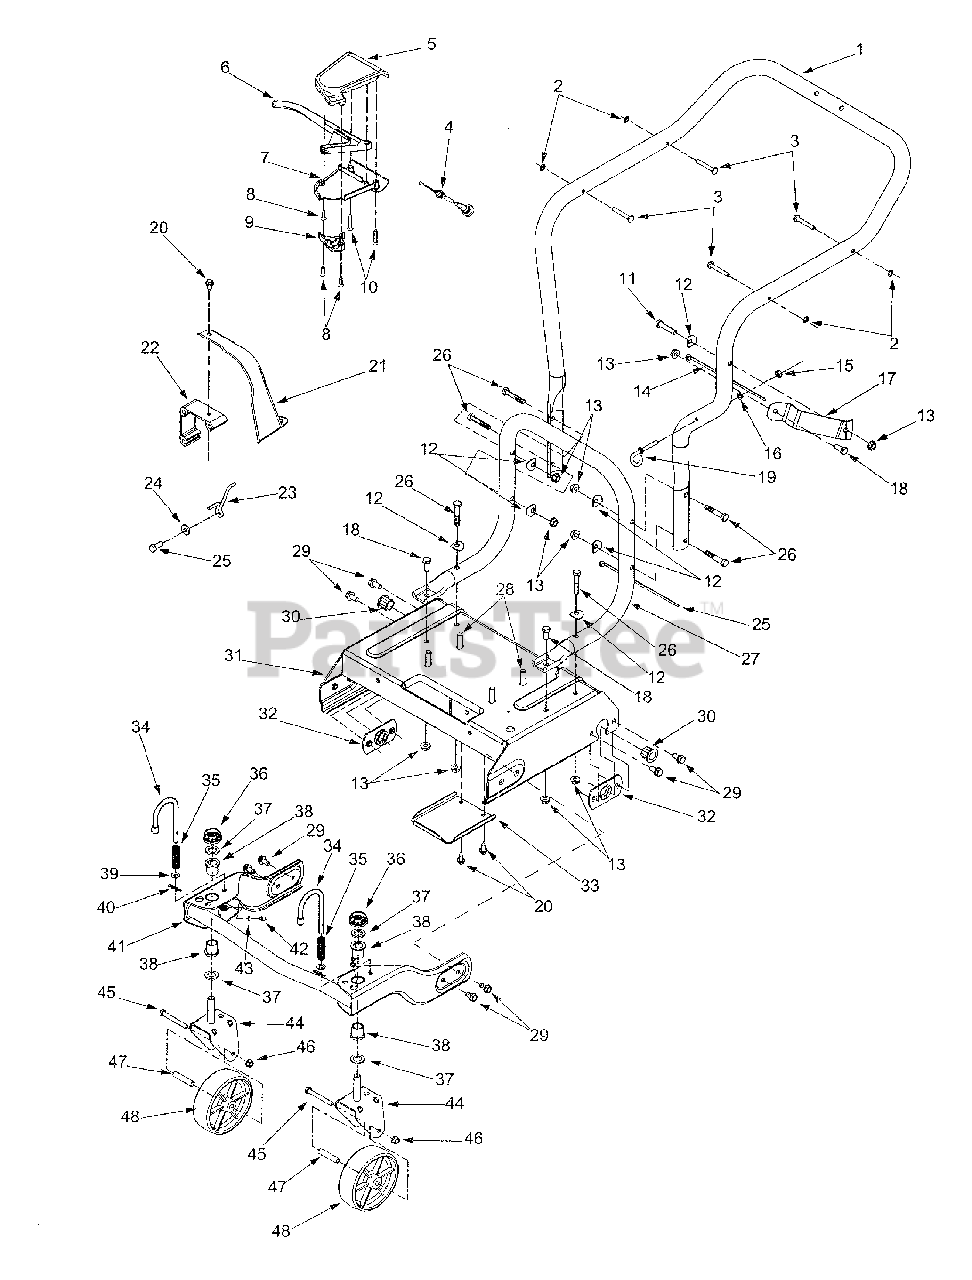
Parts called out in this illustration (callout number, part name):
3	Stud Pin .250 x 1.75
4	Clutch Cable 56"
5	Upper Clutch Cover
6	Drive Lever
7	Lower Clutch Cover
8	Screw #10-12 x .750
9	Mounting Cable Cap
10	Screw #10-16 x 1.25
11	Hex Cap Screw 5/16-18 x 1.50
12	Shoulder Washer .320 ID x .93 OD
13	Hex Flange Lock Nut 5/16-18
14	Cable Tie
15	Hex Nut 1/4-28
16	Lock Washer 1/4
18	Hex Cap Screw 5/16-18 x .75
20	Hex Washer Screw 1/4-14 x .625
21	Belt Cover
22	Engine Mounting Adapter
23	Belt Keeper
24	Flat Washer .344 x .75 x .12
25	Hex Cap Screw 5/16-24 x .75
26	Hex Cap Screw 5/16-18 x 1.75
28	Screw 3/8-16 x 1.25
29	Hex Washer Screw 5/16-18 x .625
30	Hex Flange Bearing .631 x .720
35	Compression Spring
37	Flat Washer 5/8 ID x 1.0 OD
38	Flange Bearing .632 ID
39	Flat Washer .330 ID x .630 OD
40	Cotter Pin
42	Grease Fitting 3/16
43	Flat Washer .203 ID x .403 OD
45	Hex Cap Screw 3/8-16 x 3.0
46	Flange Lock Nut 3/8-16
48	Wheel 6.0 x 2.0
